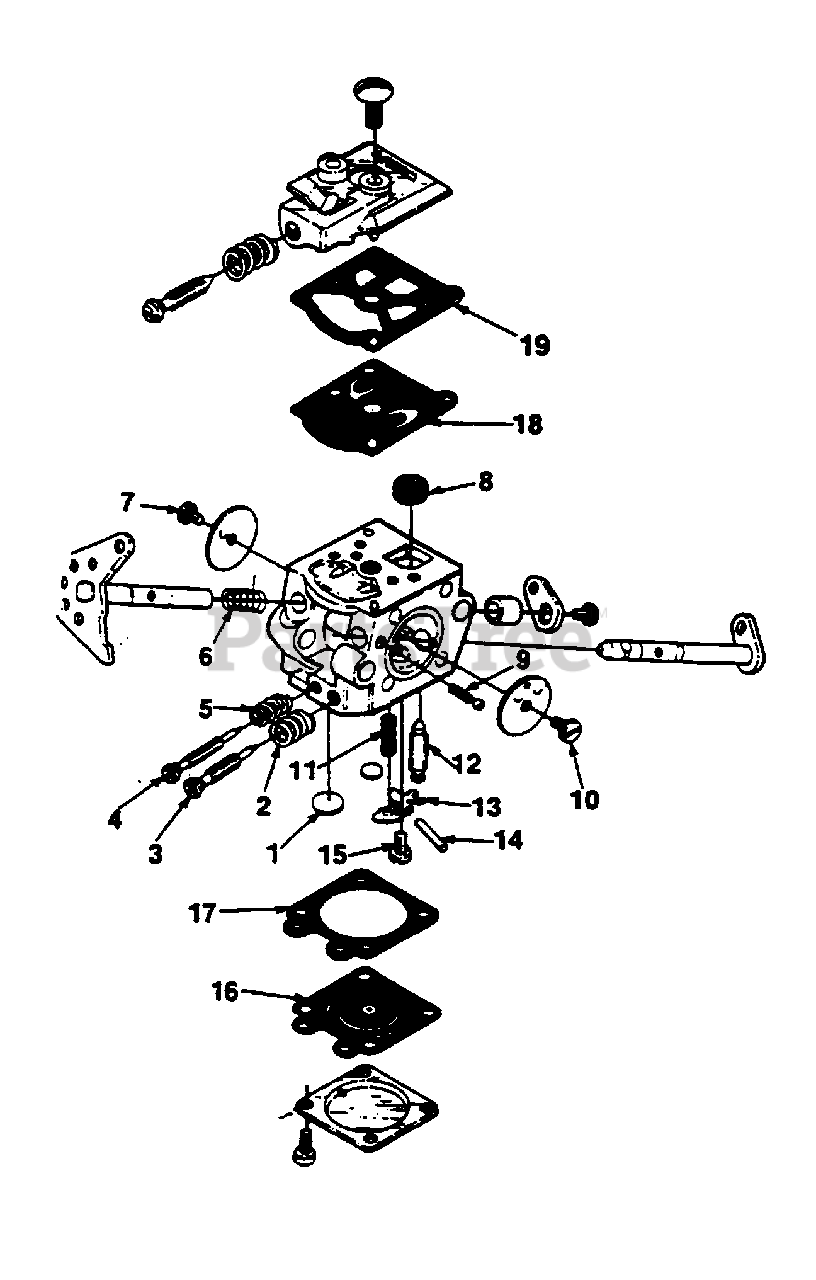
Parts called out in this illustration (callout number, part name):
1	Repair Kit
2	Repair Kit
3	Repair Kit
4	Repair Kit
5	Repair Kit
6	Repair Kit
7	Repair Kit
8	Repair Kit
9	Repair Kit
10	Repair Kit
11	Repair Kit
12	Inlet Needle
13	Repair Kit
14	Repair Kit
15	Repair Kit
16	Repair Kit
16	GASKET/Diaphragm Kit
17	Repair Kit
17	GASKET/Diaphragm Kit
18	Repair Kit
18	GASKET/Diaphragm Kit
19	Repair Kit
19	GASKET/Diaphragm Kit
